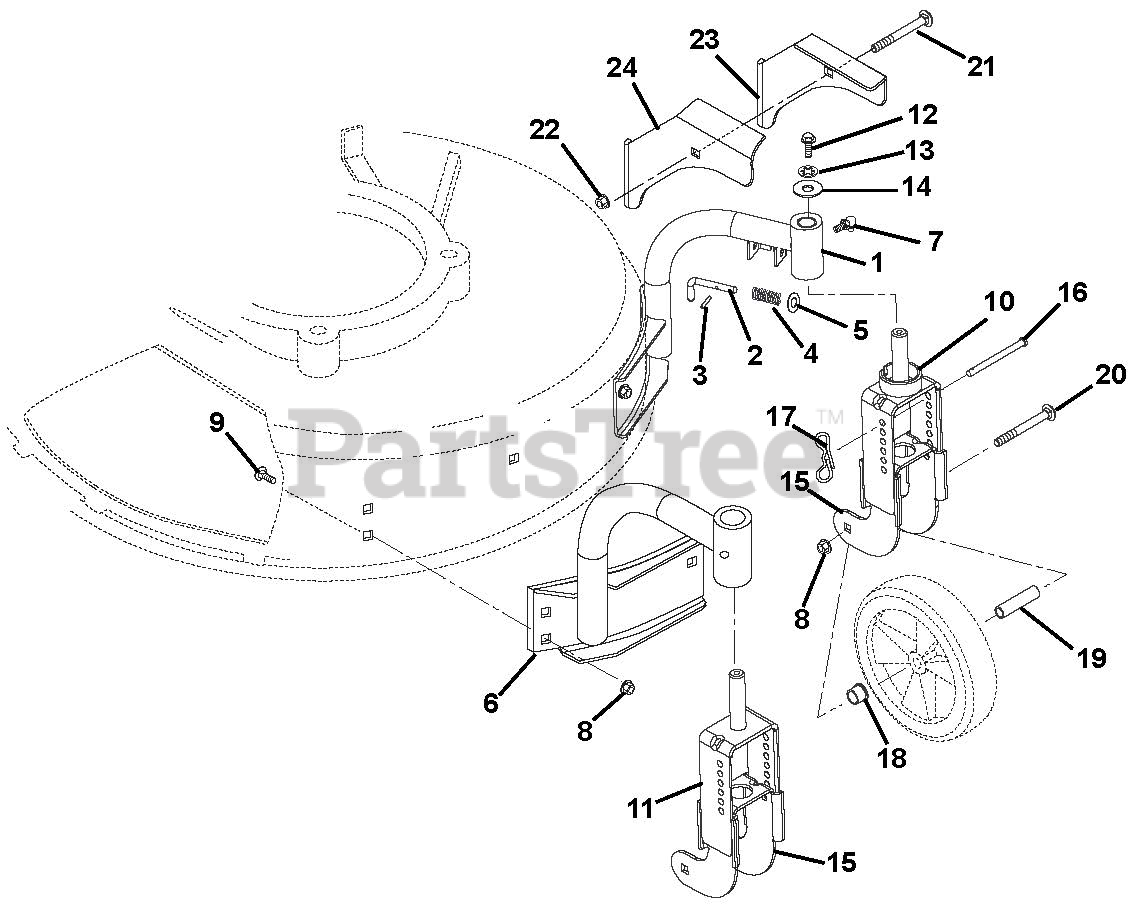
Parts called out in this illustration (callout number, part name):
1	ASSY, MOUNT LH W/BUSHINGS
2	PIN, LOCKOUT
3	PIN-ROLL .093X.50
4	SPRG, COMP--SWVL LOCKOUT
5	@WSHR-FL-STL.281X.62X.065 YWZC
6	ASSY, RH MOUNT W/BUSHINGS
7	FTG-LUBE .25-28X.256 YWZC
8	@NUT-SPNLK-FLG .312-18 YWZC
9	@BLT-RDHDSQNK .31-18X.50 G5YZ
10	YOKE, OUTER LH
11	YOKE, RH OUTER
12	@BLT-HEX .25-20X.75 GR5 YWZC
13	@WSHR-LK .25X.062 REG YWZC
14	WSHR-FL-STL .281X1.000X.063
15	YOKE-INNER
16	PIN, HEIGHT ADJUSTMENT
17	PIN, BOW TIE LOCKING COTTER
18	BSHG-FLG .500X.625X.500X.750
19	SPCR, WHEEL .385X.500X2.00
20	BLT-RDHDSQSHNK.31-18X2.75G2YWZ
21	@BLT-RDHDSQNK .25-20X1.50 G5YZ
22	@NUT-SPNLK-FLG .25-20 YWZC
23	BRACKET, HOOD CABLE--LH
24	BRACKET, HOOD CABLE WELDMENT
